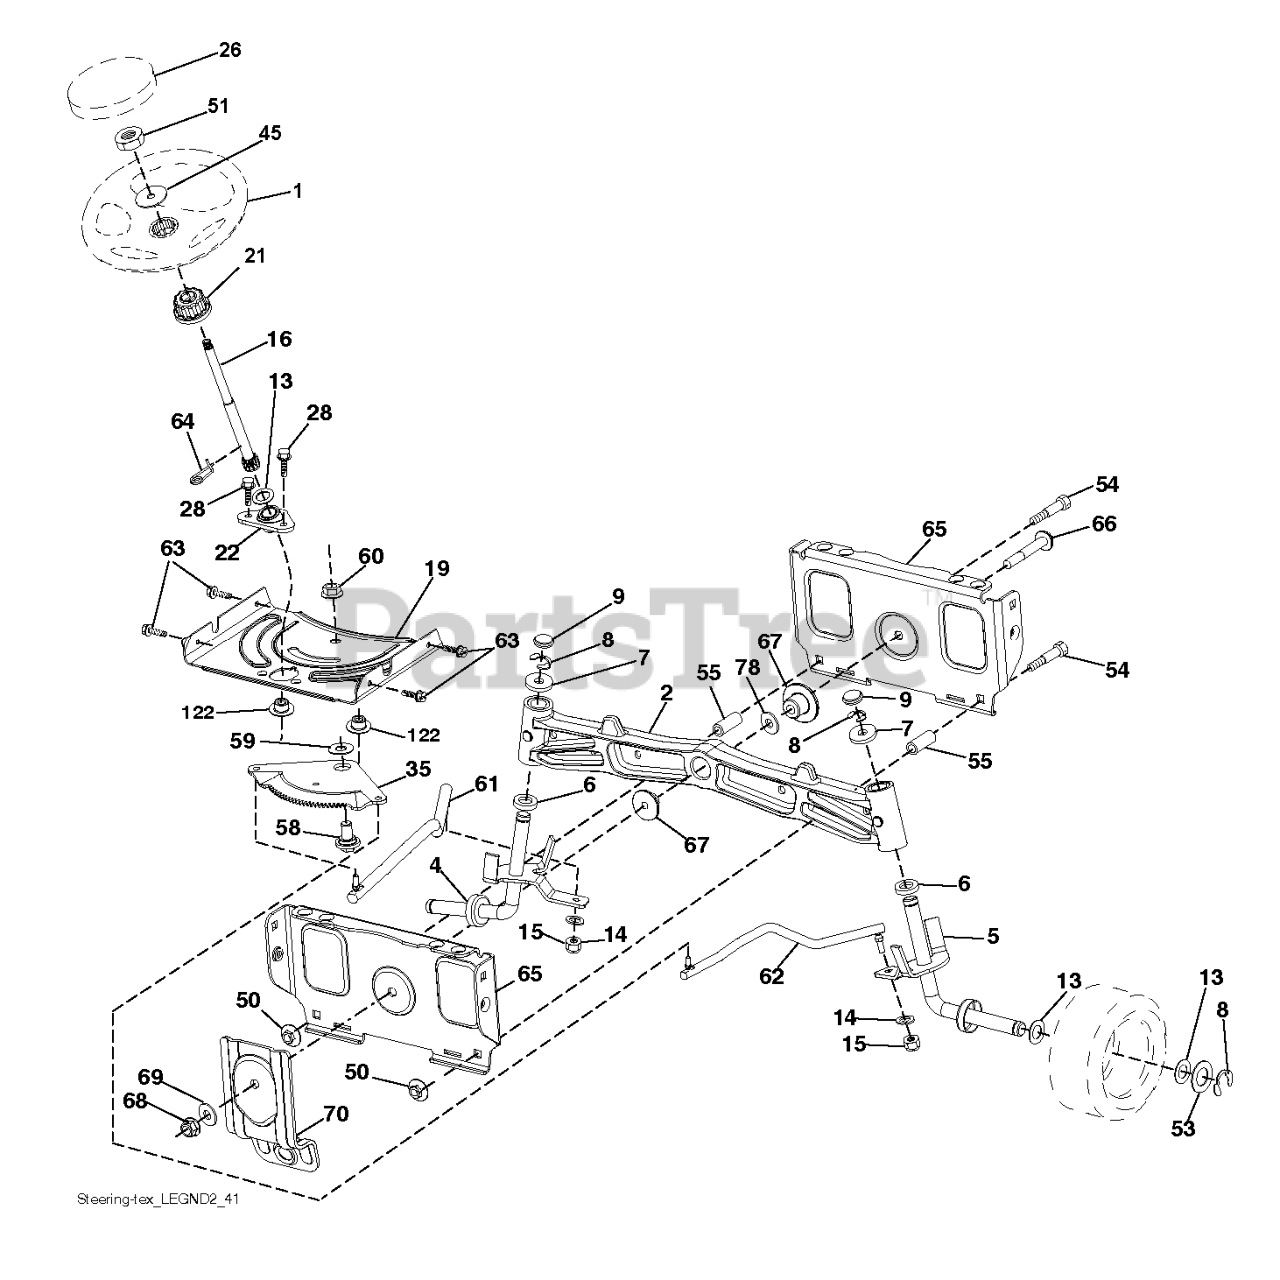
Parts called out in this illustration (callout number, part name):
1	WHEEL.STEER.HUSQ.SR.498.OVMLD
2	AXLE.CAST.IRON
4	SPINDLE.WELDED.LH.16"TEX
5	SPINDLE.WELDED.RH.16"TEX
6	THRUST WASHER
9	CAP.SPINDLE.BLACK
14	WASHER, LOCK 3/8
15	NUT CROWNLOCK 3/8-24
16	SHAFT, STEERING
19	PLATE.STEER.DDL.NLT/NG
21	ADAPTER, WHEEL STNG..
22	STEERING.SUPT.LOWER.
26	INSERT.CAP.WHL.STRG.HUSQ.PREM
28	SCREW, 3/8-16X3/4
35	GEAR.SECTOR.PLATE.DDL.
45	WASHER 9/16"ID, 2 3/8"OD
50	NUT LOCK FLG 3/8-16 UNC
51	NUT.HEX.1/2-20
53	WASHER.HARDENED
55	SPACER.BRACE.AXLE
58	BOLT.SHOULDER.SECTOR.P
59	WASHER.THURST.SECTOR.S
60	NUT FLANGE LOCK 5/8-11
61	DRAGLINK.LH.BALLSTUD.D
62	DRAGLINK.RH.BALLSTUD.D
63	SCREW
64	RETAINER.CLIP.SPRING.S
65	BRACE.AXLE.FRONT.NLT/N
66	BOLT HEX FGHD 7/16-14 X 3 SERR
67	BUSHING.PM.FRONT AXLE
68	NUT.LOCK.FLANGE.7/16
69	WASHER.1.5X.505X.118
70	BRKT.DECK.SUSPENSION.F
78	THRUST WASHER
122	CAP.GEAR.SECTOR.TEX
